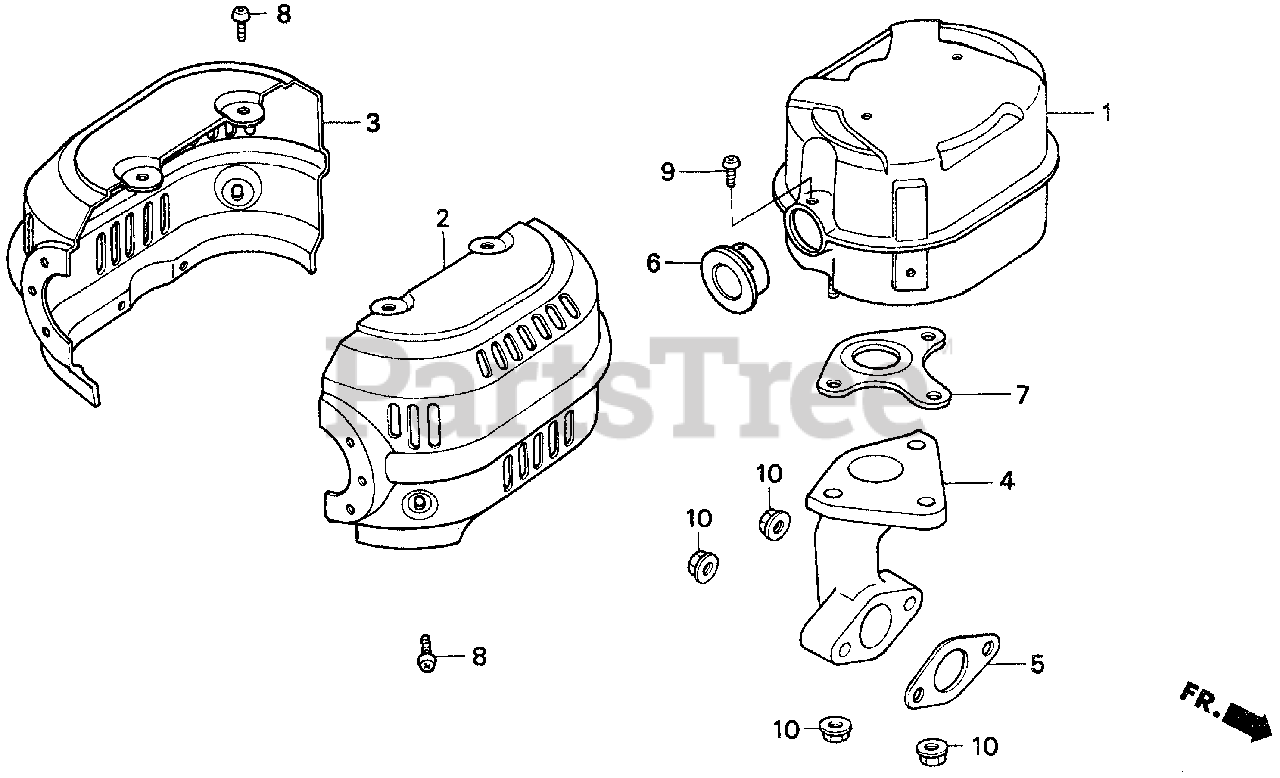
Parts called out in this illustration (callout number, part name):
1	MUFFLER (SILENT)
2	PROTECTOR, R. MUFFLER (SILENT)
3	PROTECTOR, L. MUFFLER (SILENT)
4	PIPE, EX.
5	GASKET, EX. PIPE
5	GASKET, EX. PIPE (WACKER)
6	FLANGE, BAFFLE
7	GASKET, MUFFLER
8	SCREW, TAPPING (5X8)
9	SCREW, TAPPING (4X6)
10	NUT, FLANGE (8MM)
